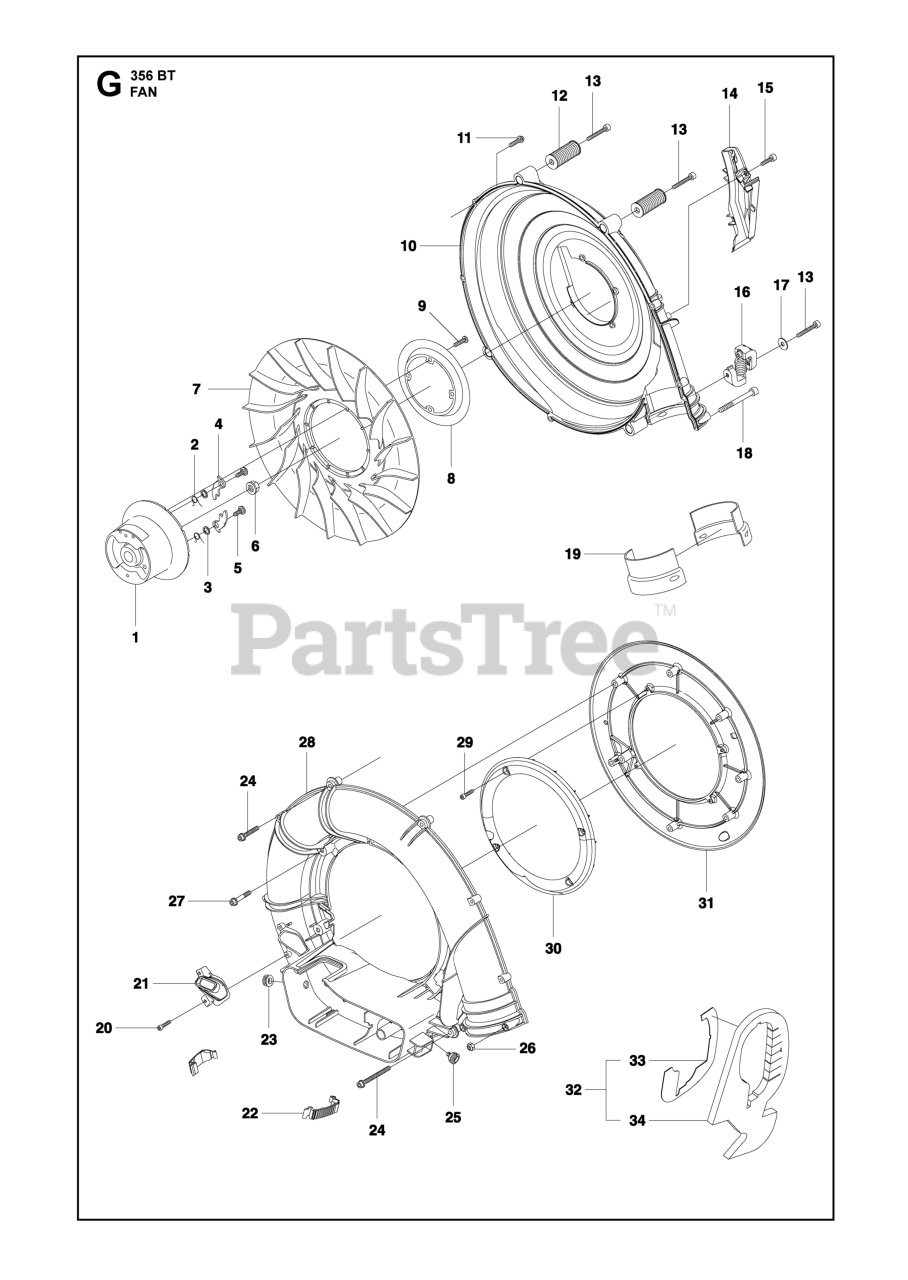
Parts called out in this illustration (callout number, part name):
5	SCREW M5X14
6	NUT W/ WASHER
14	AIR CONDUCTOR
22	BUCKLE ORANGE
33	TAPE DOUBLE-STICK
